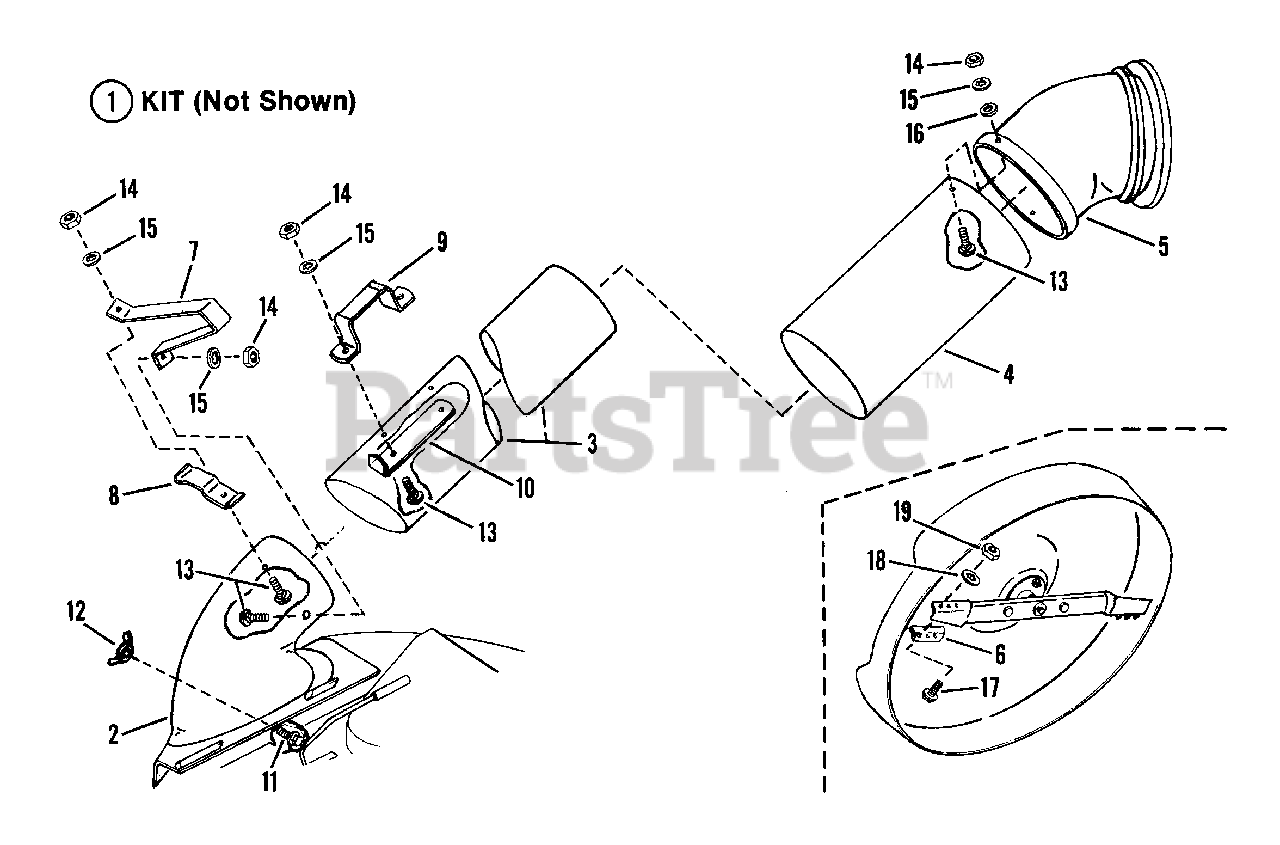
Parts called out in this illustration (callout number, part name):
1	KIT, Snapper Bag-N-Wagon (Complete)
2	ADAPTER, Deck
3	TUBE, Grass (8" Dia.)
4	TUBE, Grass (10" Dia.)
5	ELBOW, Grass Tube
6	AIR-LIFT, Blade
7	BRACKET, Stand-Off
8	LATCH, Tube
9	HANDLE, Tube
10	BASE, Tube Handle
11	CARRIAGE BOLT, 5/16-18x1/2"
12	WING-NUT, 5/16-18
13	CARRIAGE BOLT, 1/4-20x3/4"
14	NUT, 1/4-20 Hex
15	LOCKWASHER, 1/4 Internal Tooth
16	WASHER, 5/16 SAE
17	SCREW, 5/16-24x21/32"
18	LOCKWASHER, 5/16 Internal Tooth
19	NUT, 5/16-24 Hex
